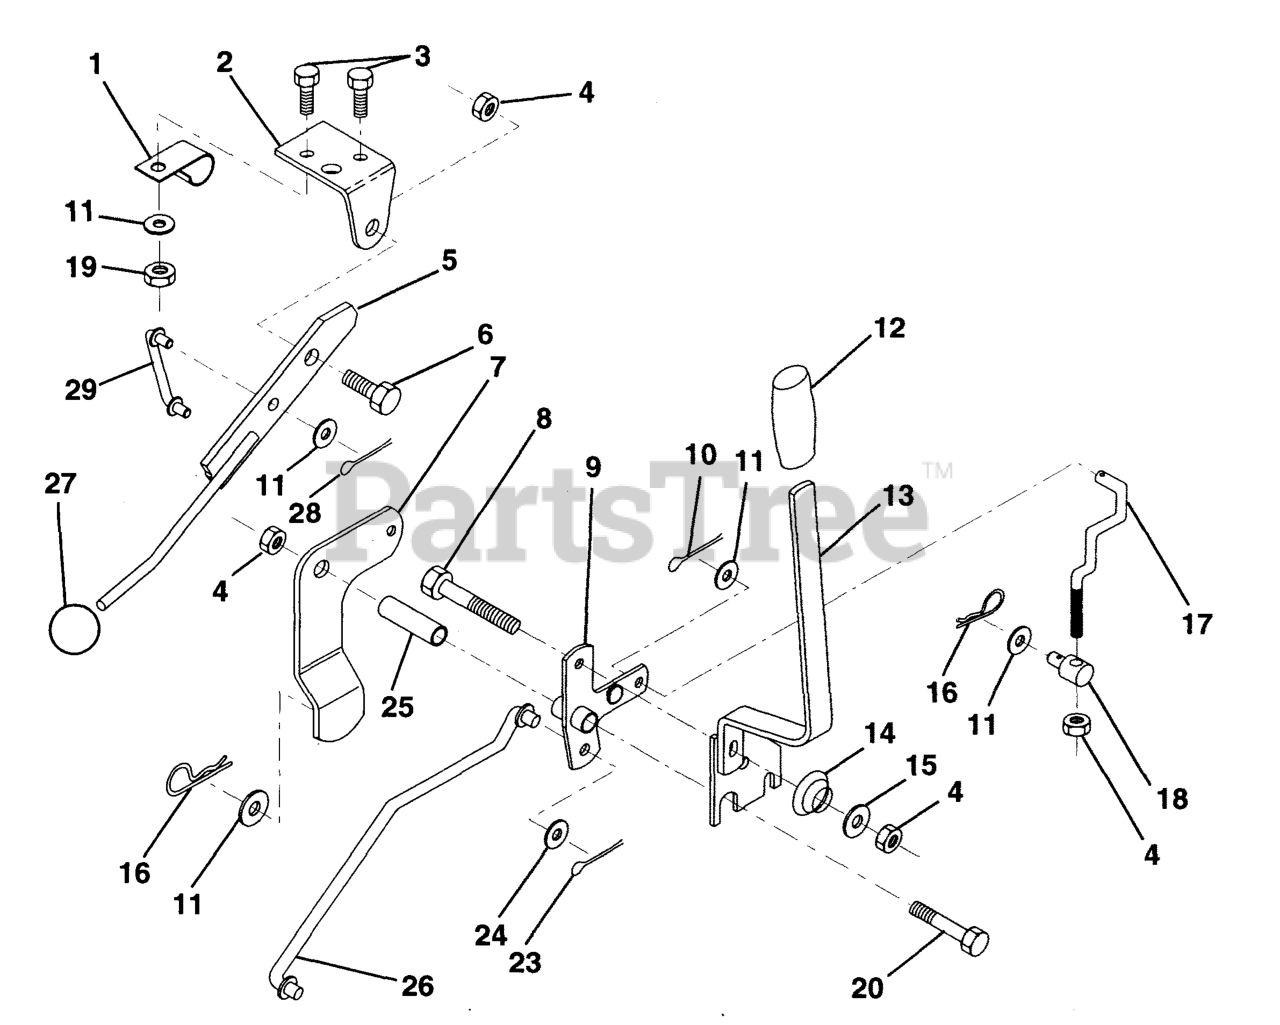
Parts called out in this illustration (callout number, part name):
1	CLIP,INSULATOR
2	BRKT CLUTCH
3	BOLT
5	CLUTCH LEVER ASSY
6	BOLT, SHOULDER LT
7	ASSEMBLY MOWER CLUTCH ARM
9	BELLCRANK,LIFT
10	COTTER PIN
11	WASHER
12	HANDLE GRIP
13	HDLE, LIFT T
14	SPRING COMPRESSIO
15	WASHER T
16	SPRING TI
17	LINK LIFT FRT
18	TRUNION
19	NUT.CROWNLOCK.1/4
23	PIN COTTER
24	WASHER
25	TUBE SPACER
26	ROD,MOWER LIFT
27	KNOB T (3/8 HOLE)
28	COTTER PIN
29	LINK MOWER CLUTCH
